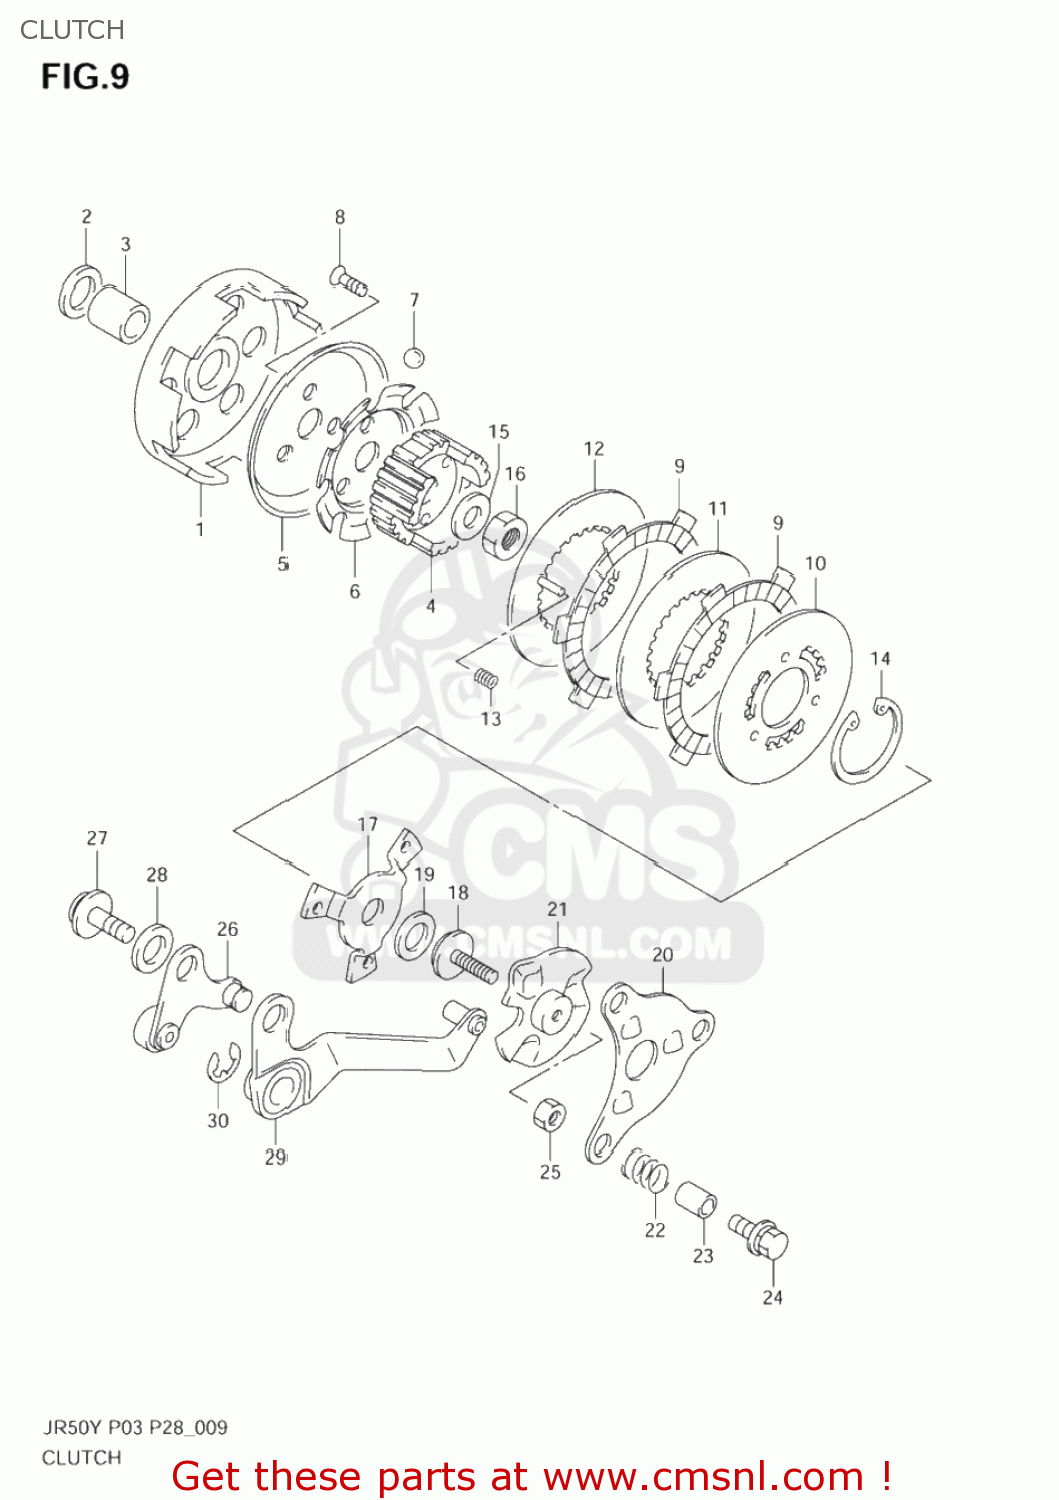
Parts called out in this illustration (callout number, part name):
1	GEAR,PRIMARY DRIVE
2	WASHER(14X23X3)
3	SPACER(14X19X18)
4	HUB,CLUTCH SLEEVE
5	PLATE,CLUTCH BALL
6	GUIDE,CLUTCH BALL
7	BALL
8	SCREW ,6X16
9	PLATE,CLUTCH DRIVE (NAS)
10	PLATE,CLUTCH DRIVEN OUTER (NAS)
11	PLATE,CLUTCH DRIVEN (NAS)
12	PLATE,CLUTCH INNER
13	SPRING
14	CIRCLIP
15	WASHER
16	NUT
17	PLATE,CLUTCH PRESSURE
18	PIECE,CLUTCH PUSH
19	BEARING(10X22X2.8)
20	PLATE,CLUTCH RELEASE
21	PLATE,CLUTCH RELEASE,INNER
22	SPRING
23	SPACER(6X9X10.3)
24	BOLT
25	NUT 6MM
26	PLATE,CLUTCH RELEASE ARM LINK
27	BOLT(8X17)
28	SHIM(8X16X1)
29	ARM,CLUTCH RELEASE PLATE
30	E RING
